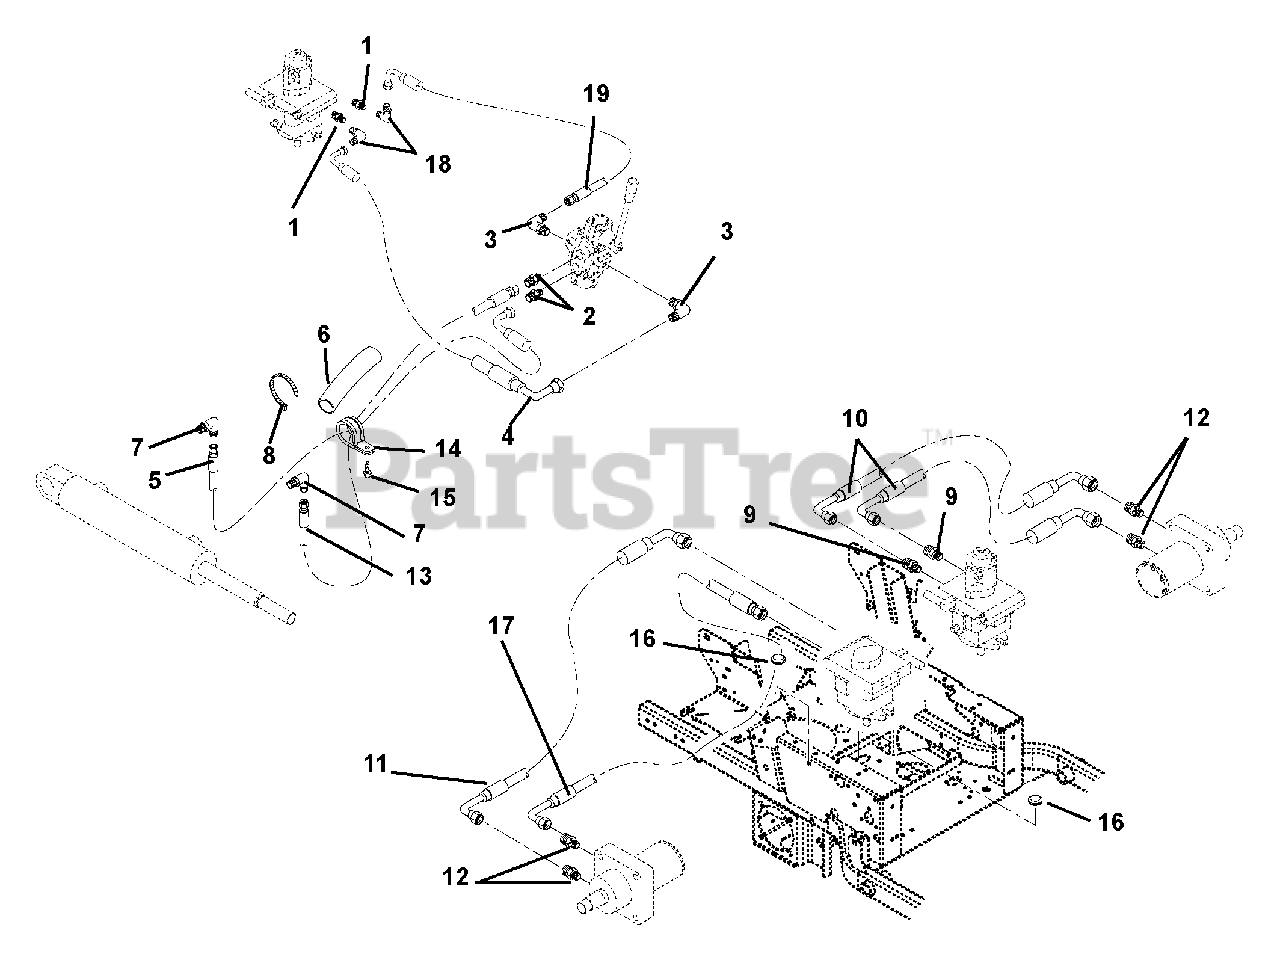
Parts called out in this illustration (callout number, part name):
1	FITTING, HYD (4 F5OLO)
2	FITTING, HYD (4-6 F5OLO)
3	FTG, HYD ELBOW M4F-M8O
4	HOSE,HYD .25-19-2K F04F9-F04F9
5	HOSE,HYD .25-47-2K FO4F0-FO4F0
6	SLEEVE, PROTECTIVE
7	FITTING, HYD (4 C5OLO)
8	CABLE TIE LG 5-1/2
9	ADPTR,FACE SEAL 8X8 1/2 O-RING
10	HOSE,HYD .50-19-2K F08F9-F08F9
11	HOSE,HYD .50-20-2K F08F0-F08F0
12	FTG, HYD STR M10O-M8F
13	HOSE,HYD.25-42-2K F04F0-F04F4
14	CLAMP, COUSHIONED STEEL REV
15	@SCR-TAP .25-20X.50 HWH TR YWZ
16	GROMMET 1.25ID X 1.5OD
17	HOSE,HYD .50-17-2K F08F0-F08F9
18	FTG, HYD ELBOW F4F-M4O
19	HOSE,HYD .25-15-2K F04F9-F04F0
